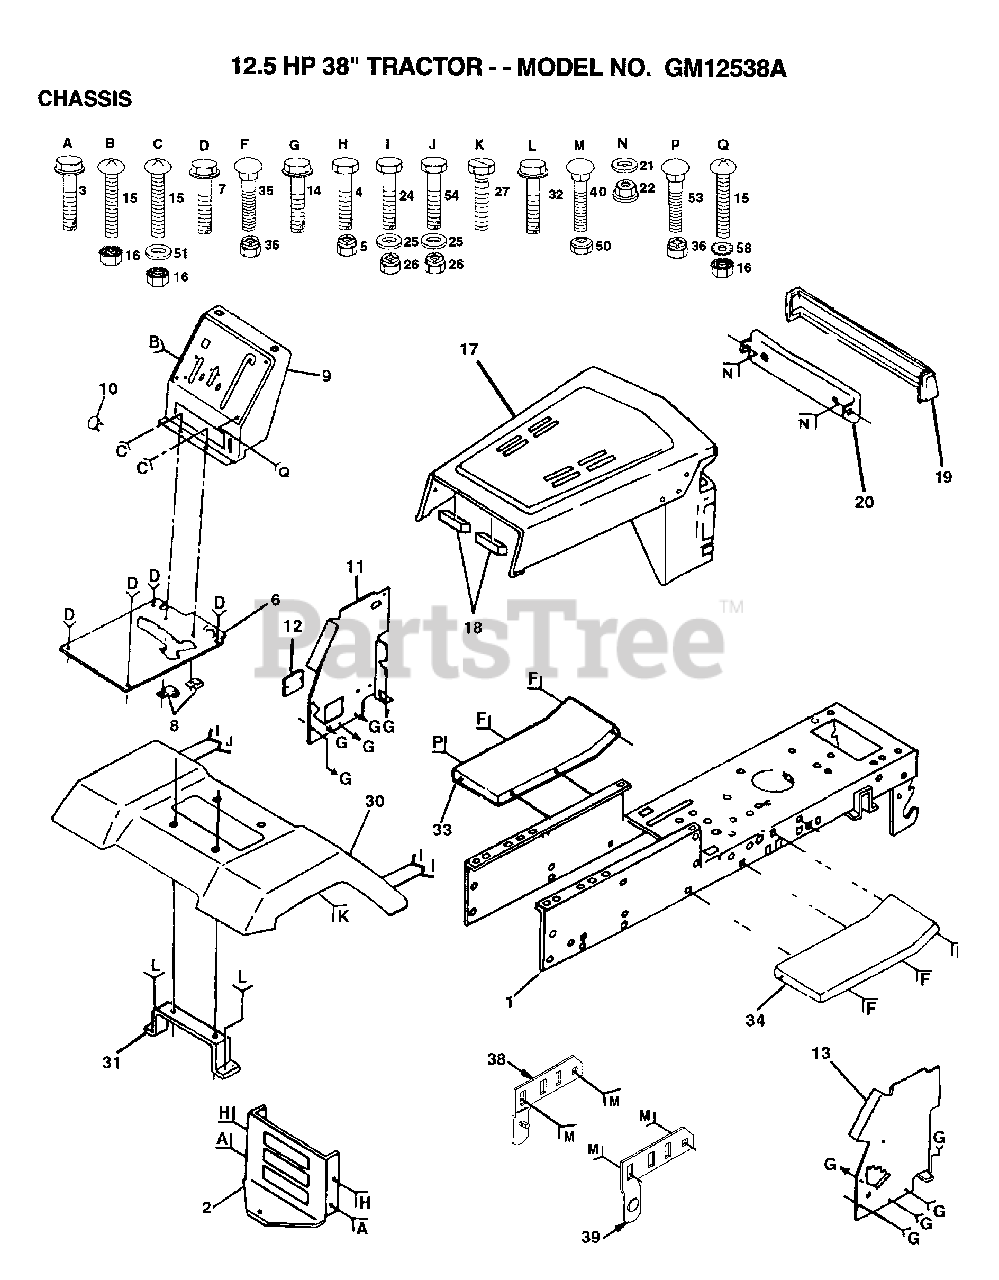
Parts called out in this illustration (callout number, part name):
3	SCREW
7	SCREW LT
8	CLIP T
10	PLUG BUTTON T
11	PANEL DASH LH
12	COVER ACCESS
14	SCREW LT
15	SCREW
17	HOOD/GRILL.ASM
19	LENS SERVICE KIT
21	WASHER PM
22	PAL NUT LT
25	WASHER
27	SCREW LT
31	BRKT FENDER
32	SCREW
33	FOOTREST.LH
34	FOOTREST.RH
35	BOLT
38	BRKT ASM PIVOT LH
39	BRKT ASM PIVOT RH
50	NUT
51	WASHER
58	LOCKWASHER
